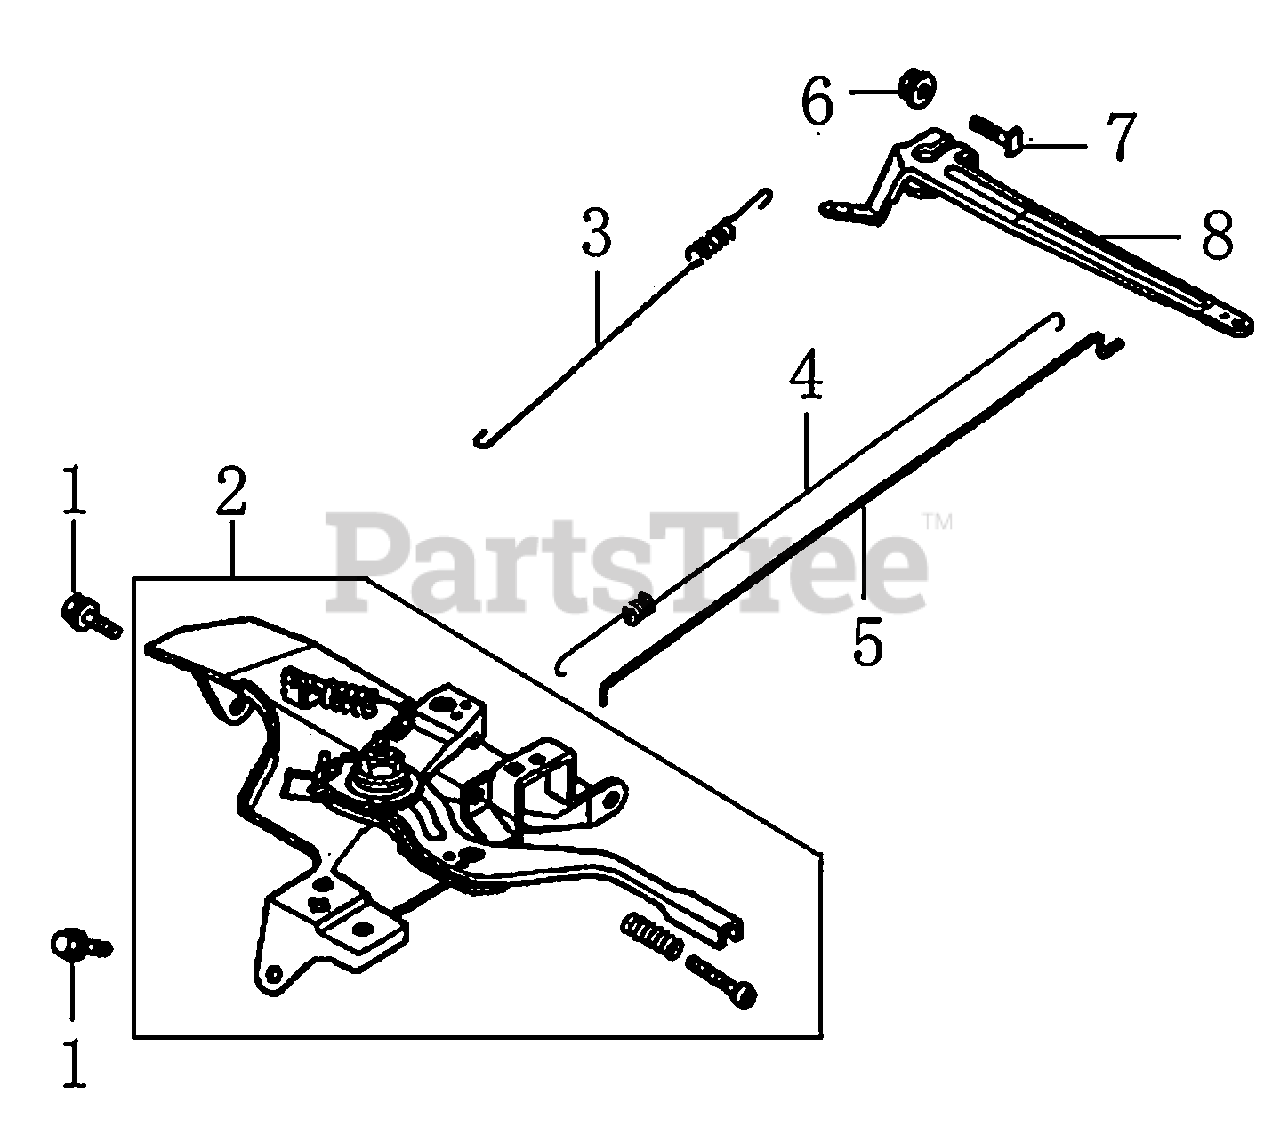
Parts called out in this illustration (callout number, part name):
1	NUT, FLANGE M6
2	CONTROL ASSY.
3	SPRING, CABLE RETURN
4	SPRING, THROTTLE RETURN
5	ROD, GOVERNOR
6	NUT, FLANGE M6
7	BOLT, QUADRATE HEAD
8	ARM, GOVERNOR
